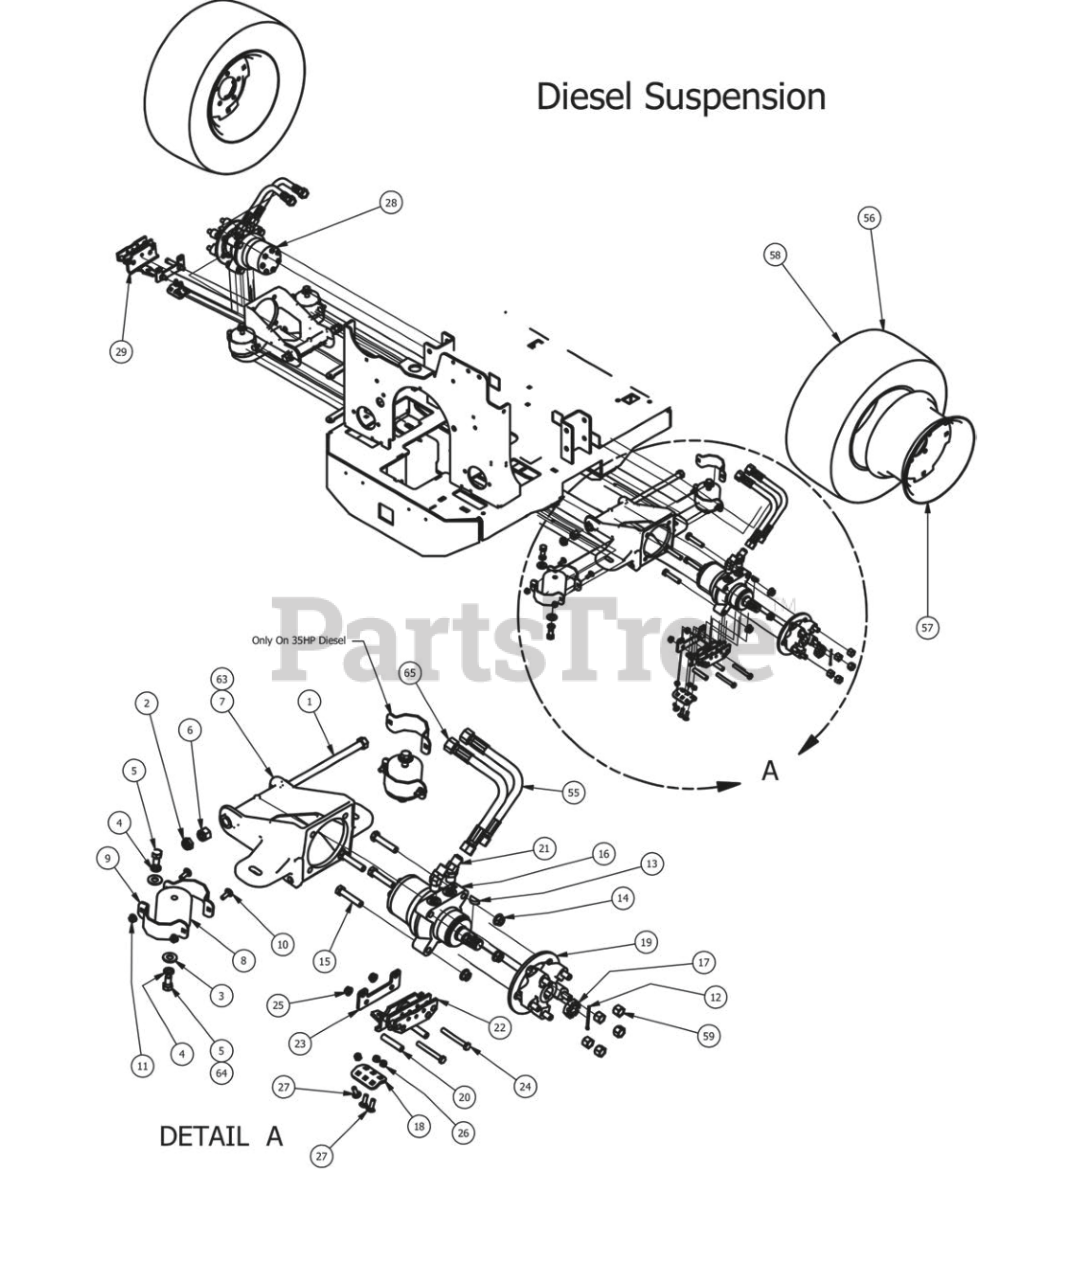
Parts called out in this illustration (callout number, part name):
1	5/8"x10" Hex Bolt (Grade8)
2	5/8" Nylock (1/2 Jam)
3	1/2" Washer (Grade 8)
4	1/2" Lock Washer
5	1/2" x 1" Hex Bolt
6	5/8 Std NC Nylock Nut
7	60" Suspension Kit Wheel Motor
8	Vibration Mount-Blue Dot
9	Isolator Band Clamp
10	5/16" x 1" Carriage Bolt
11	5/16" Nylock Flange Nut
12	1/8x2-1/4 cotter pin Zinc
13	Woodruff Key
14	1/2" Flange Nut
15	1/2" x 2 1/2" Hex Bolt
16	18cc Parker Wheel Motor- Right
17	1" Castle Nut for Wheel Motor
18	Ausco Brake Clable Bracket
19	Drum Brake Hub & Rotor Assembly
20	Ausco Brake Spacer
21	45 Degree Fitting 31704-10-10
22	Right Brake Caliper
23	Ausco Caliper Mounting Bracket
24	3/8-16x3 grade 5 hex bolt
25	3/8" Flange Nut
26	3/8 Std NC Nylock Nut
27	5/16" x 1" Carriage Bolt
28	18cc Parker Wheel Motor- Left
29	Left Brake Caliper
30	5 VIdler Pulley-BCVI-81
31	5/8" x 2 1/2" Hex Bolt
32	5/8" x 1/" Collar Spacer
33	5/8 Std NC Nylock Nut
34	Diesel Back Pump Cover 2008 and up
35	5/16" x 3/4" Button Head Bolt
36	Pump Cover Hinge
37	5/16-18 x 3/4 Carriage Bolt
38	5/8 Round Insert
39	Diesel Back Pump Cover 2008
40	1/4" x 5/8" Buttonhead Bolt
41	1/4" Nylock Nut
42	5/16" Flange Nut
43	5/16" x 1" Carriage Bolt
44	360 ID Plastic Washer
45	.360 ID Plastic Washer
46	Diesel Hood 3 Cyl
47	5/16" Knob
48	5/16-18 Nylon Insert Locknut
49	5/16" x 1" Bolt
50	5/16" x 1 1/4" Carriage Bolt
51	5/16" Flange Nut
52	8" Rubber Bumper
53	1/4" x 1 1/2" Self Tapping Screw
54	1/4" Flat Washer
55	26" Hose Assembly with Adaptors
56	26 x 12.00-12 Tire and Orange Wheel Assembly
57	12 x 10.5 Wheel AOS Rear
58	26 x 12.00-12 Tire
59	Acorn Lug Nut
60	1024 X 5/8" Buttonhead Bolt
61	Steel Pump Cover Latch
62	#10 Nylock Nut
63	72" Suspension Kit Wheel Motor
64	1/2-13 1-1/4 Hex Bolt Only On 60" Suspension Kit wheel Motor
65	26" Hose Only
66	Diesel Hoood 4cyl
